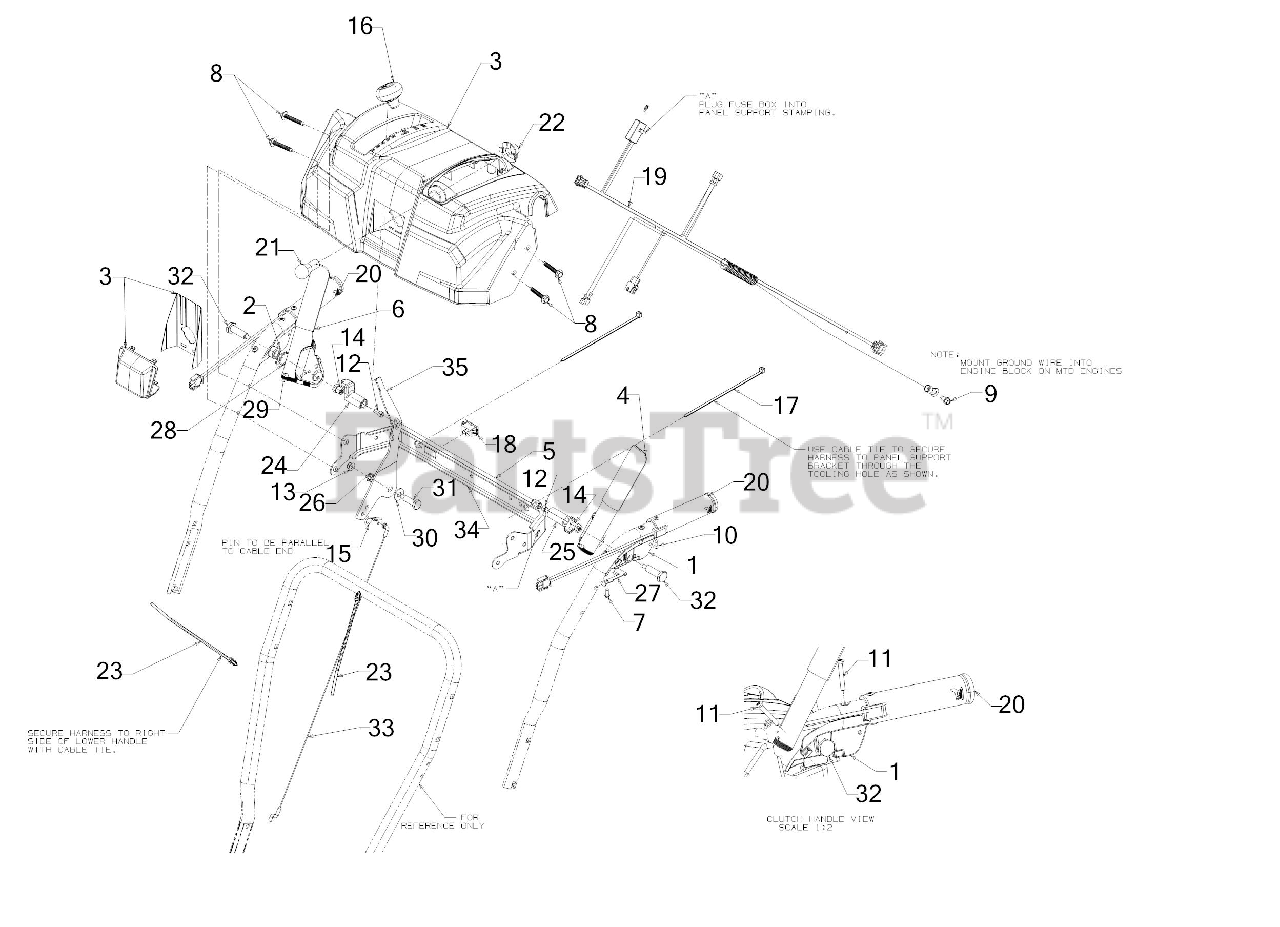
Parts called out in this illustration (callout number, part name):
1	CLUTCH LOCK HANDLE ASSEMBLY (LH)
2	CLUTCH LOCK HANDLE ASSEMBLY (RH)
3	HANDLE PANEL ASSEMBLY (TROY-BILT)
4	HANDLE ASSEMBLY (LH)
6	ENGAGEMENT HANDLE ASSEMBLY (RH) (BLACK)
7	SCREW #8-16 x .50
8	SCREW 1/4-20 x 1.625
9	SCREW 1/4-20 X.500
10	SCREW #10-16 x .625
11	SCREW #10-24 x 1.375
12	SCREW 1/4-20 x .50
13	FLANGE LOCK NUT
14	HEX NUT W/PATCH
15	INTERNAL COTTER PIN
16	SHIFT KNOB
17	7" CABLE TIE
18	HEATED GRIP SWITCH
19	HEATED GRIP HARNESS
22	HEADLIGHT SOCKET
23	PUSH MOUNT TIE
25	CLUTCH LOCK CAM
26	COMPRESSION SPRING
27	CLUTCH SPRING
28	TORSION SPRING
29	RUBBER BUMPER
30	FLAT WASHER
31	SHOULDER SCREW
32	SHOULDER SCREW .437 x 1.345 1/4-20
33	SPEED SELECTOR CABLE (PLASTIC)
34	HANDLE SUPPORT BRACKET
